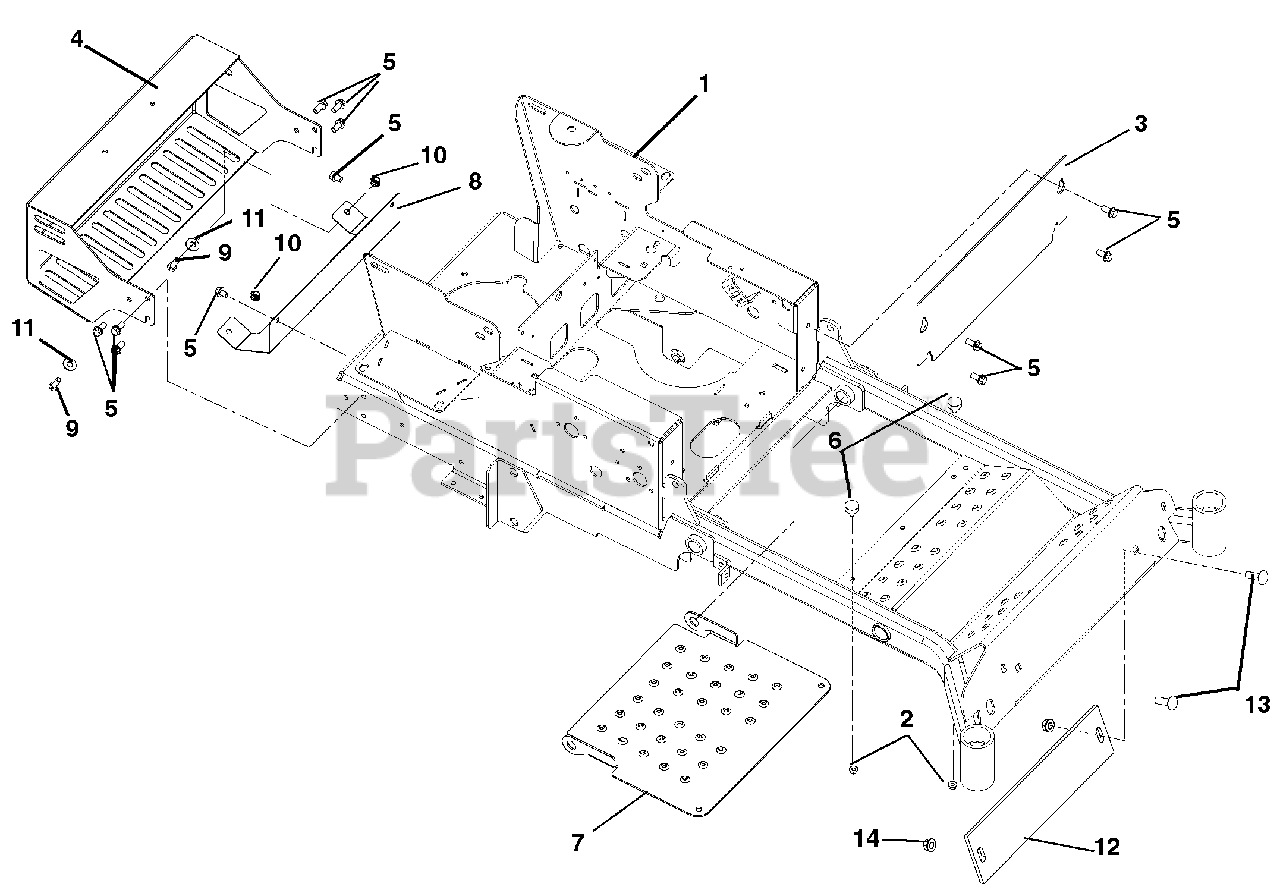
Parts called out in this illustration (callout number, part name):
1	Weldment, CZ 44-48 Main Frame
2	Nut, Spin Lock Flange .312-18
3	Kick Plate
4	Weldment Gravely, CZ Bumper
5	Screw, Tapping .38-16 x .75 Hex Washer Head
6	Bumper, Rubber
7	Panel, Inspection
8	Heat Shield
9	Bolt, Hex .38-16 x 1.00 Grade 5
10	Nut, Nyloc Flange .38-16
11	Washer, Flat Steel .438 x 1.00 x .083
12	Counterwieght CZ Front- Red
13	Bolt, Round Head Square Neck .50-13 x 1.75 Grade 5
14	Nut .50-13 Nyloc Flange
